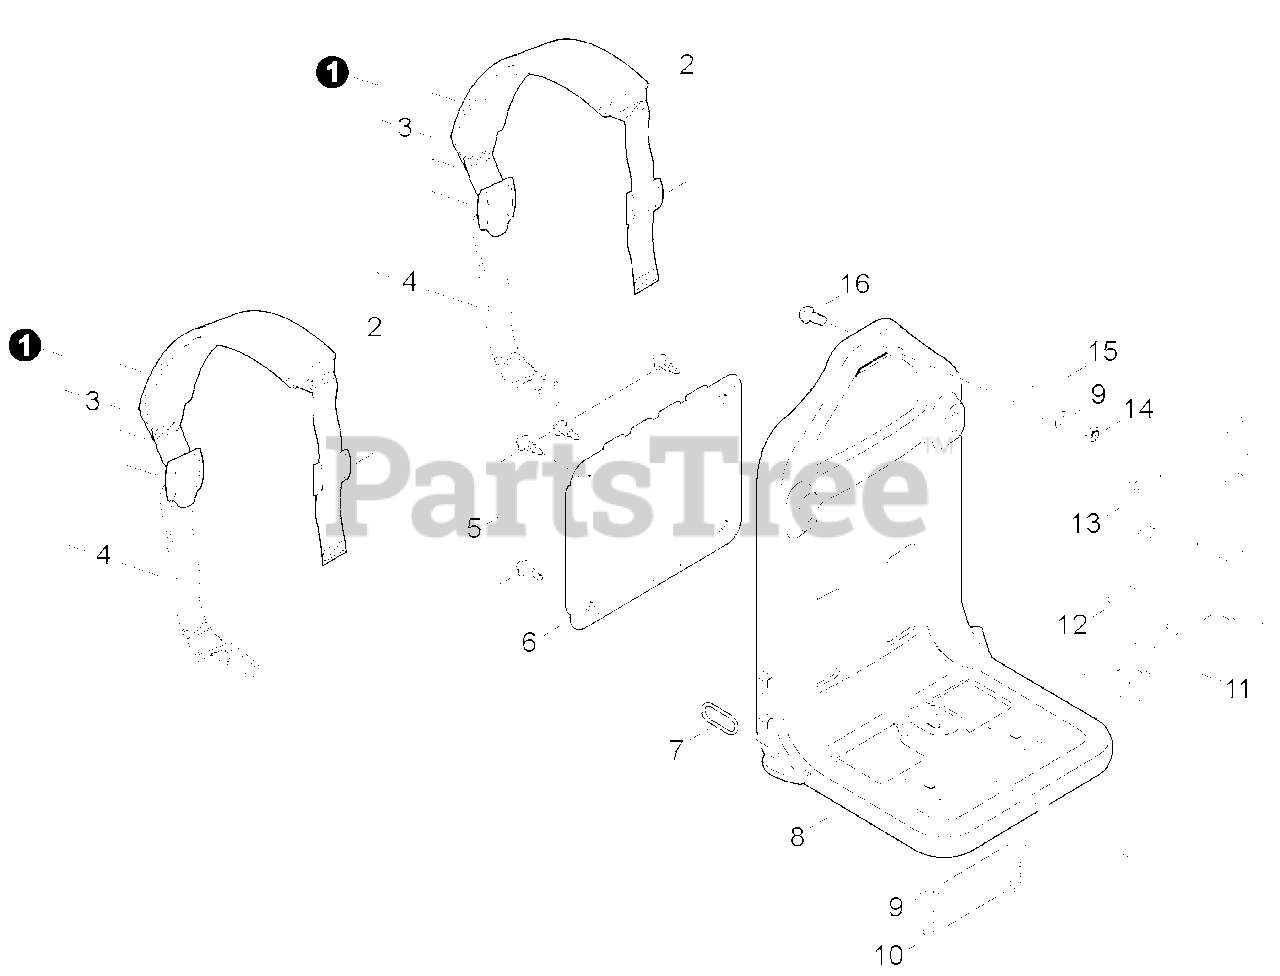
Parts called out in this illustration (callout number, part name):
1	HARNESS ASSY
3	HARNESS
4	STRAP, HARNESS
6	PAD, BACKPACK
7	RING, HARNESS
8	FRAME, BACKPACK
9	COLLAR Ø18ר6.4×L2
10	BOLT M6×20
11	CUSHION
12	BRACKET
13	CUSHION
15	HANGER, HARNESS
16	SCREW, TRUSS M6×30
